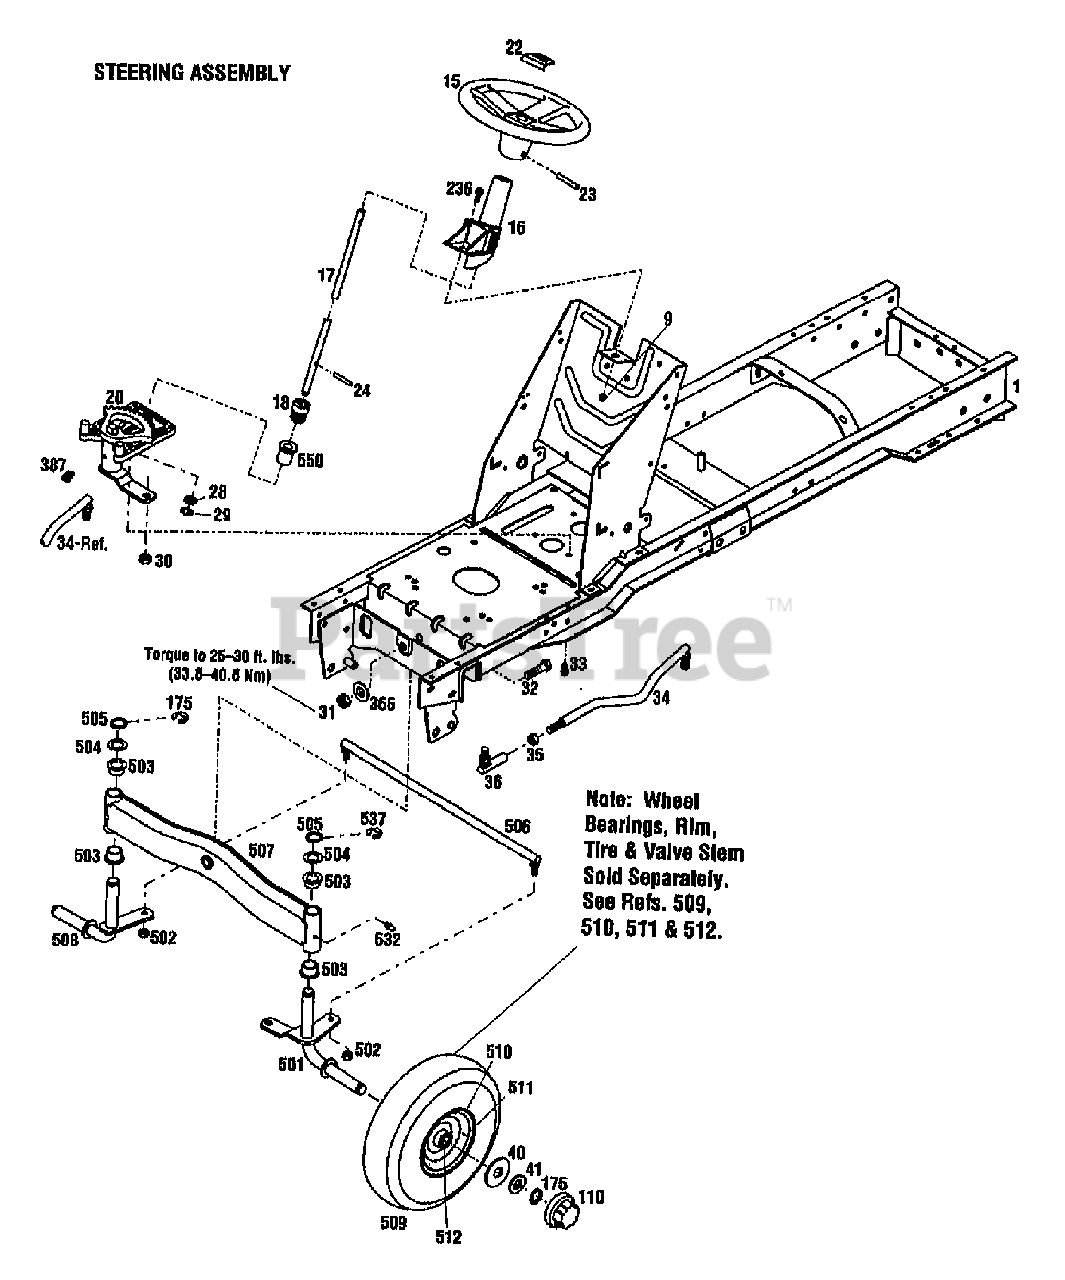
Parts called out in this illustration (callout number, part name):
1	ASSM-FRAME LTX
9	NUT-HFLK 5/16-18 ZP
15	WHEEL-STEERING
16	SUPPORT-STEERING SHAFT
17	SHAFT-STEERING
18	GEAR-PINION
20	ASSM-STEERING GEAR
22	CAP-STEERING
23	PIN-ROLL .25X2.25
24	PIN-ROLL 1/4 X 1-1/4
28	WASHER-1.0X.64X.09
29	RING-RETAINING
30	NUT-HEX/JAM 1/2-20
31	NUT-H/LK 5/8-11
32	SCR-HH
33	SCR-HFLK 5/16-18X.75
34	LINK-DRAG
35	NUT-JAM
36	JOINT-BALL
40	WASHER-SPEC .75X2.50
41	WASHER-1.38 X.765X .06 ZP
110	CAP-HUB
175	RING-RET."E".577 ID
236	SCR-HFLK 5/16-18X.75 ZP
366	WASHER-1.75X.687X.134 ZP
387	FITTING-GREASE 90 DEGREE
501	ASSM-SPINDLE LH
502	NUT-LOCK
504	WASHER-1.25X.765X.049
505	RING-HEAVY EXT HD 1.0 ID
506	KIT-TIE ROD W/HDW
508	ASSM-SPINDLE WHEEL RH
509	TIRE 15X6.00-6RS
510	DISC WHEEL
511	STEM-VALVE
512	BEARINGS-WHEEL
532	FITTING-GREASE 1/4-28X2.00
550	BEARING
